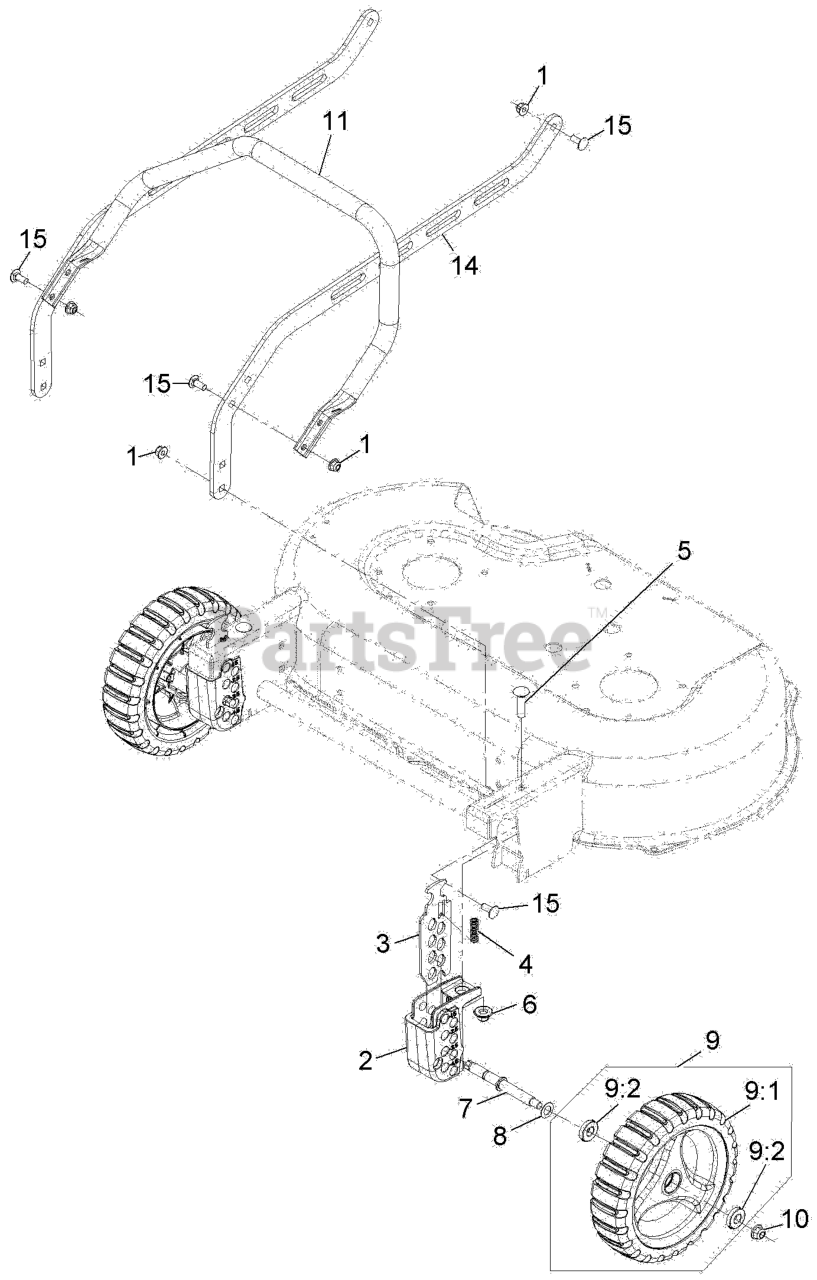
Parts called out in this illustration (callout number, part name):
1	NUT-HF, NI
2	BLOCK-FRONT QUADRANT
3	PLATE, FRONT HEIGHT
4	SPRING-COMPRESSION
5	SCREW-CARR
6	Nut-Nyloc 3/8-16 Flg
7	AXLE-WHEEL
8	WASHER-PLAIN
9:2	BEARING-BALL
10	NUT-HF, NI
11	GUARD-ENGINE
15	SCREW-CARR
